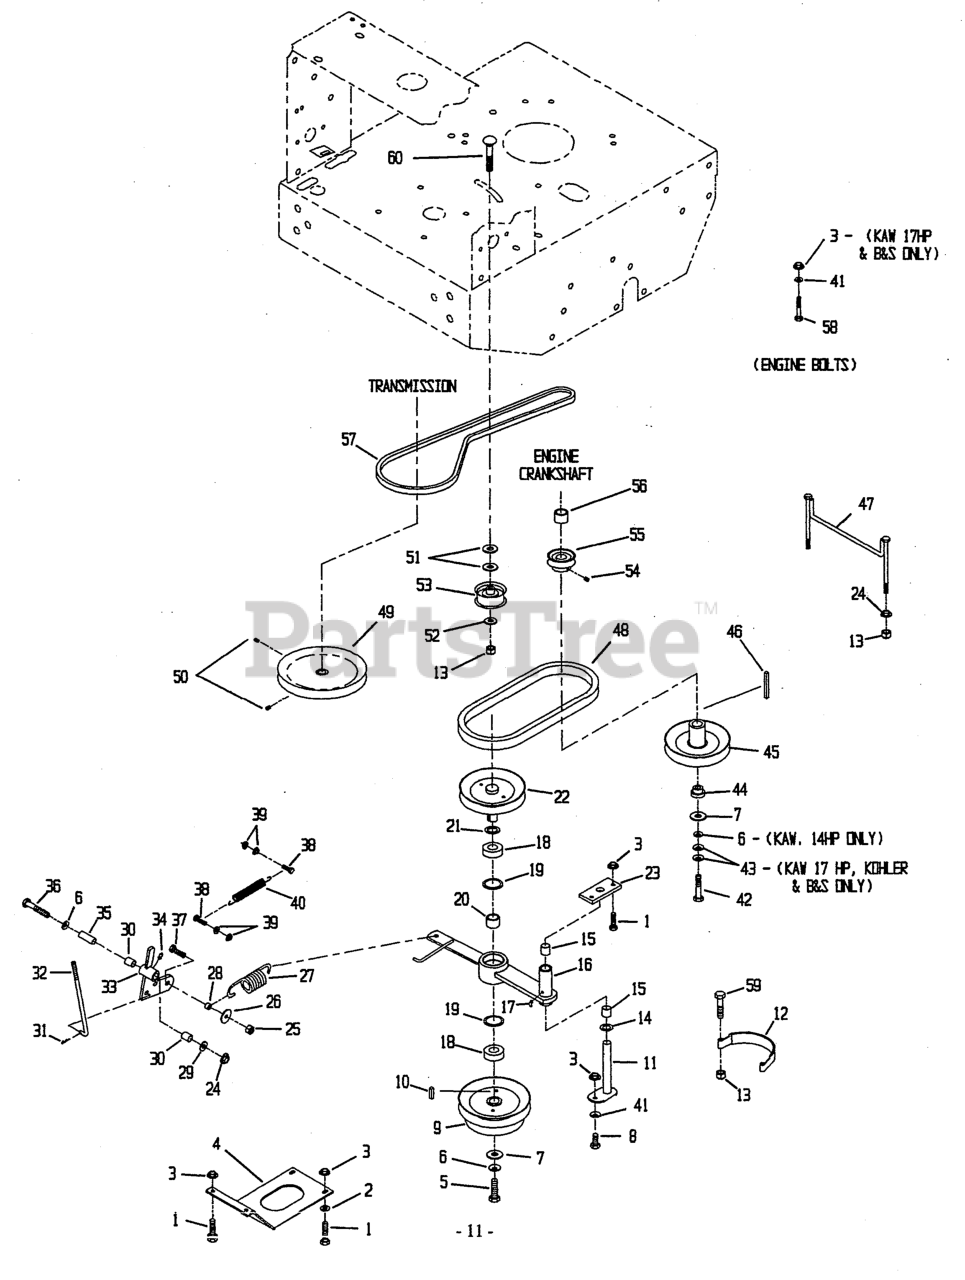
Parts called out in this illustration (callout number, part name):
1	Screw, Hex Cap 5/16-18x1
2	Washer, Flat Std 5/16
3	Nut, Whizlck 5/16-18
4	Plate, Guard
5	Screw, Hex Cap 3/8-24x1 G8
6	Washer, Disc Spring 3/8
7	Washer, Swivel
8	Screw, Hex Cap 5/16-18x3/4
9	Sheave, W/Drum (36" & 52")
10	Key, Mach 1/4x1/4x1
11	Pivot Pin Wldmnt
12	Band, Brake Clutch
13	Nut, Nyloc 3/8-16
14	Washer, Spacer
15	Pivot, Bearing
16	Arm Weldmt, Clutch
17	Zerk, 1/4-28x45
18	Bearing, Clutch Shaft
19	Ring, Snap
20	Spacer, Bearing Clutch
21	Washer, Spacer
22	Sheave W/Shaft
23	Plate, Clutch Pivot
24	Nut, Whizlock 3/8-16
25	Nut, Nyloc 5/16-18
26	Washer, Strut
27	Spring, Belt Tension
28	Spacer, Clutch Anchor
29	Washer, Flat Std 3/8
30	Pivot, Bearing
31	Pin, Hair Cotter 0585 #2
32	Linkage, Lower
33	Link Pivot W/Bearing
34	Zerk, Straight 1/4-28
35	Bushing, Idler Pivot
36	Screw, Hex Cap 3/8-16x2-1/4
37	Screw, Hex Cap 5/16-18x1-1/4
38	Screw, Hex Cap 1/4-20x1
39	Nut, Whizlock 1/4-20
40	Spring, Motion Contral
41	Washer, Disc Spring 5/16
42	Screw, Hex Cap M10x1.55x55 Mm
43	Disc, Spring 7/16
44	Bushing, Clutch Keeper
45	Sheave, Engine
46	Key, Machine 1/4x1/4x2-5/8
47	Guide, Belt Weldmt
48	Belt, Blade Clutch
49	Sheave, Transmission
50	Screw, Set 1/4-20x3/8
51	Washer, Flat Std 7/16
52	Washer, Flat SAE 3/8
53	Idler, Transmission Drive
54	Screw, Set 5/16-18x3/8
55	Sheave, Transmission Drive
56	Spacer, Crankshaft
57	Belt, Transmission Drive
58	Screw, Hex Cap 5/16-18x1 1/2
59	Screw, Hex Cap 3/8-16x1 1/2
60	Bolt, Carriage Ssn 3/8-16x2
